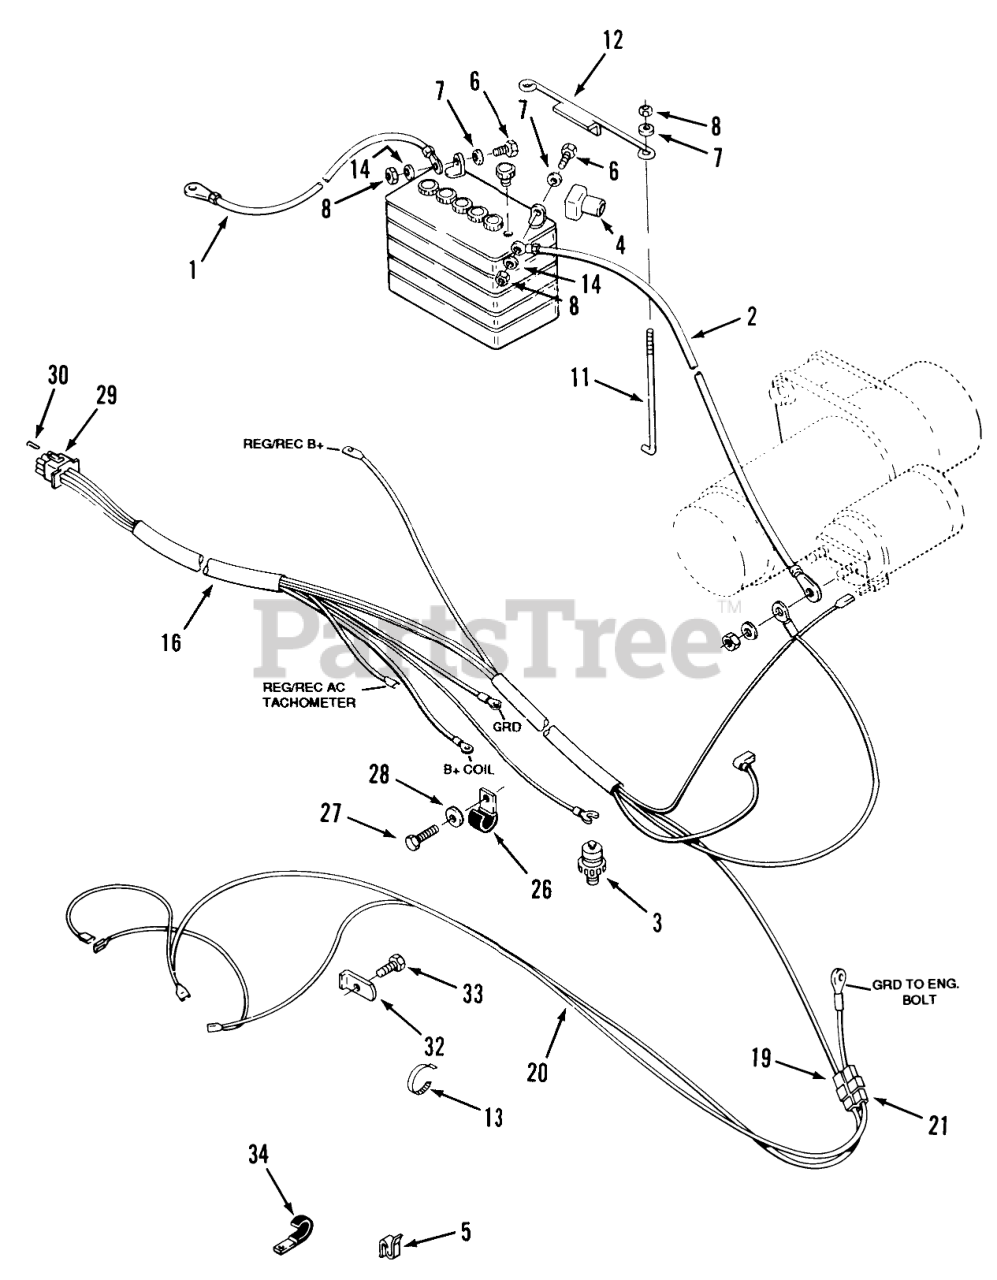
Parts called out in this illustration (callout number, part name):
1	ASS'Y-WIRE
2	SHIELD-SD DISCHARGE
3	SWITCH
4	Boot
5	SPEED CLIP
6	SCREW-HH
7	WASHER-FLAT
8	Nut
11	HOOK-BATTERY RETAIN
12	HOLDDOWN-BATTERY
13	PLASTIC TIE
16	Engine Wiring Harness
19	MALE CONNECTOR
20	HARNESS-HEADLIGHT
21	CONNECTOR BODY
26	Clip
27	Bolt
28	LOCKWASHER 1/4 IT
29	CONNECTOR CAP
30	CONTACT SOCKET
32	LOCK-HEADLIGHT
33	Bolt
34	CLIP
